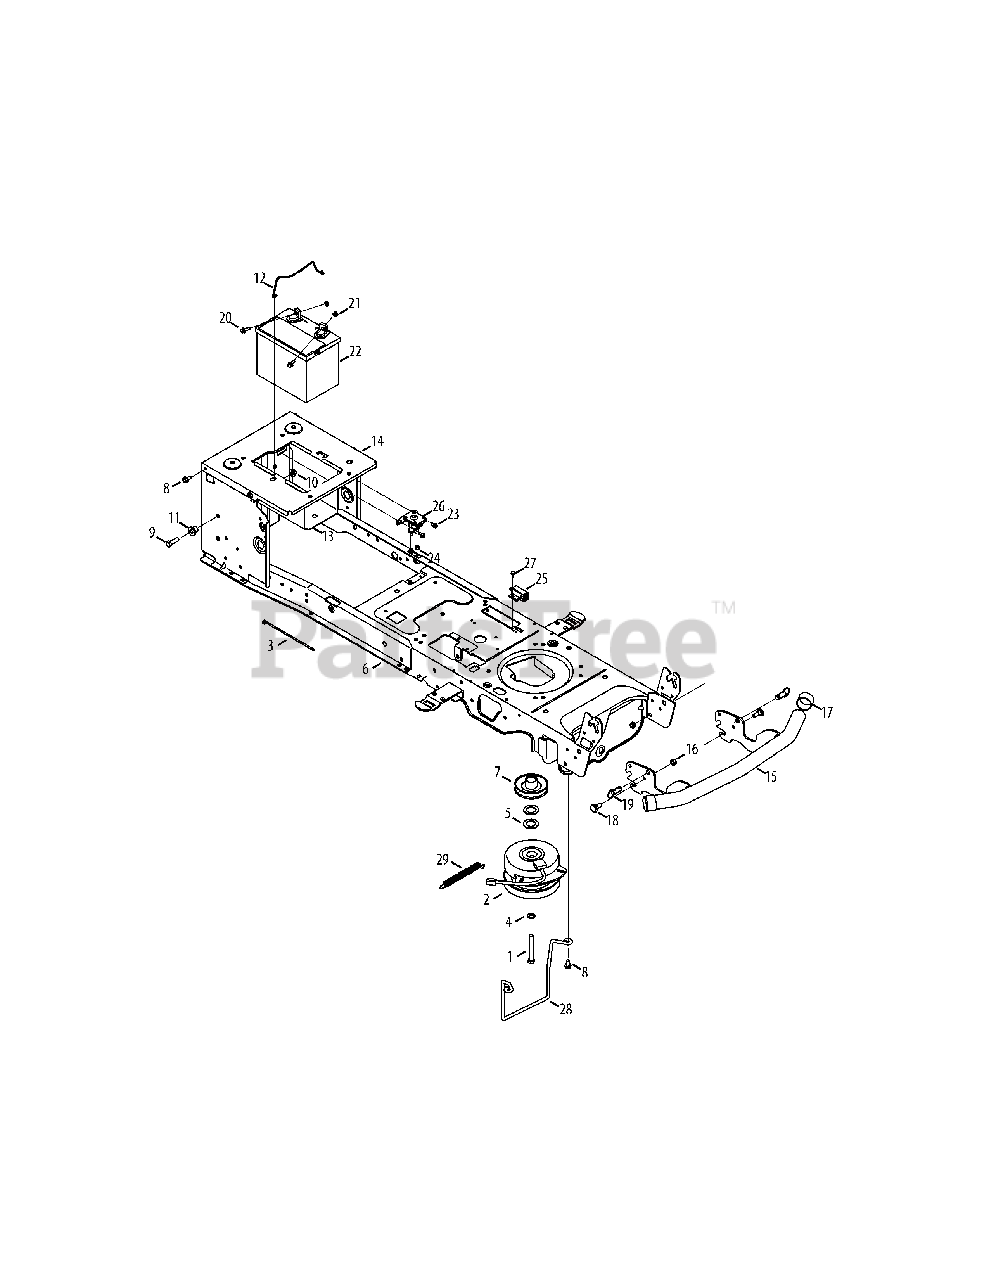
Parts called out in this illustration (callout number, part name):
1	Hex Head Screw, 7/16-20:3.50
2	Electric PTO Clutch
3	Cable Tie, 3/16 x .05 x 7.4
4	Lock Washer, 7/16
5	Flat Washer, 1.031 x 1.620 x .095
6	Frame
7	Electric PTO Engine Pulley
8	Taptite Screw, 5/16-18:.750
9	Hex Head Screw, 3/8-16:1.25
10	Flangelock Nut, 3/8-16
11	Shoulder Spacer, .38 x 1.0 x .70
12	Battery Holder Rod
16	Hexlock Nut, 3/8-16
17	Bumper Cap
18	Shoulder Bolt, .496 x .336
19	Quick Release Pin
20	Hex Head Flange, 1/4-20:.75
21	Sems Nut, 1/4-20
22	Battery
23	Taptite Screw, 1/4-20:0.375
24	Flangelock Nut, 1/4-20
25	Interlock Switch
26	Solenoid, 12 V
27	Shoulder Screw, #10-32:.500
28	Belt Keeper Rod
29	Spring, Extn, .56 Dia X 5.52
